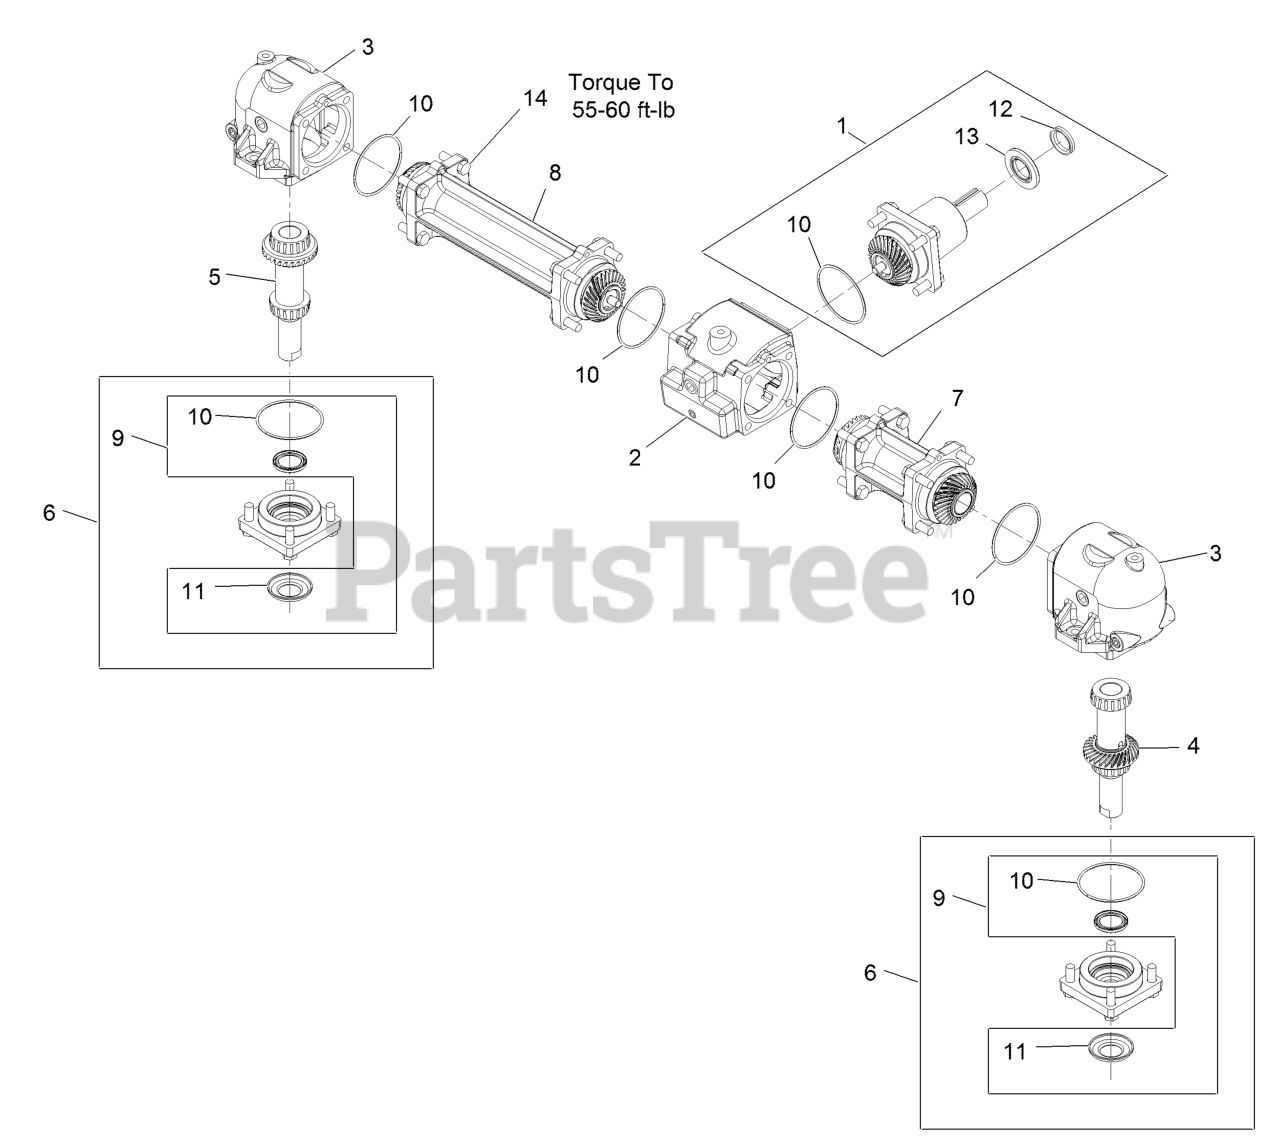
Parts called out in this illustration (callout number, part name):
1	INPUT PINION ASM
2	HOUSING-CENTER
3	HOUSING-END
4	LH OUTPUT SHAFT AND GEAR
5	RH OUTPUT SHAFT AND GEAR
6	CAP-OUTPUT
7	TUBE-CONNECTOR, SHORT
8	TUBE-CONNECTOR, LONG
9	OUTPUT SEAL KIT
10	SEAL-O-RING
11	WASHER-CUPPED
12	SEAL-V-RING
13	SEAL-INPUT
